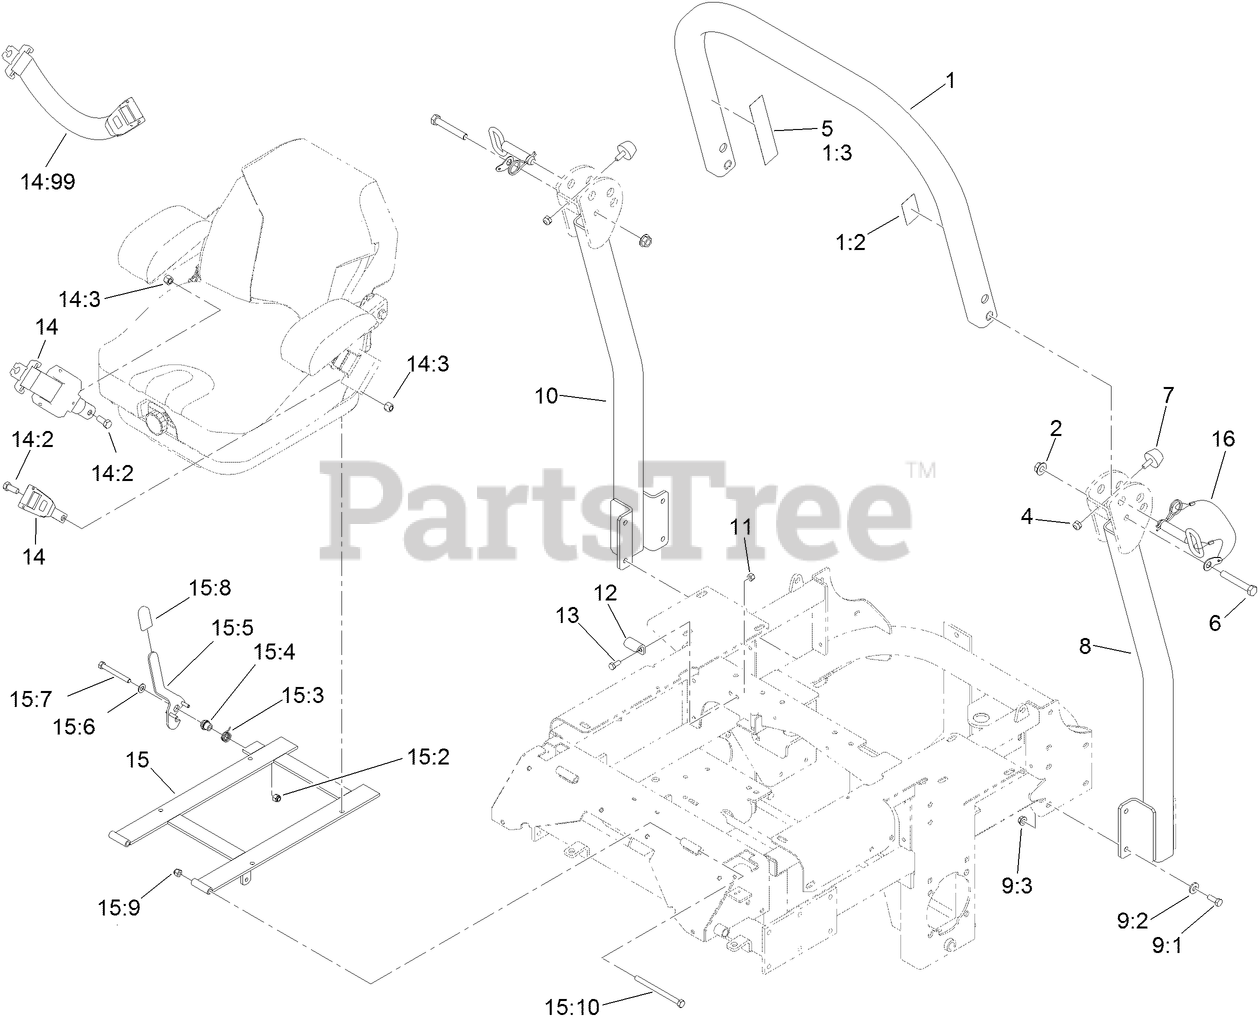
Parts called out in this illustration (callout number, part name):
1	Deck ASM
1:2	DECAL-ROPS
1:3	DECAL-WARNING, FOLDING ROPS
2	NUT-HF
4	NUT-LOCK, NI
5	DECAL-WARNING
6	SCREW-HH
7	BUMPER-RUBBER
8	Deck ASM
9	Deck ASM
9:1	SCREW-HH
9:2	WASHER-BELLEVILLE
9:3	NUT-HHF, WHIZ
10	Deck ASM
11	NUT-LOCK, NI
12	CATCH-LATCH, SEAT
13	SCREW-HH
14	RETRACTABLE SEATBELT KIT
14:2	SCREW-HH
14:3	NUT-LOCK
14:99	SEAT BELT EXTENSION KIT
15	SEATFRAME ASM
15:2	NUT-LOCK, NI
15:3	SPRING-TORSION
15:4	BUSHING-LATCH, SEAT
15:5	LATCH ASM
15:6	WASHER-FLAT
15:7	SCREW-HH
15:8	GRIP-LEVER
15:9	NUT-LOCK, NI
15:10	SCREW-HH
16	PIN-FOLD, ROPS
